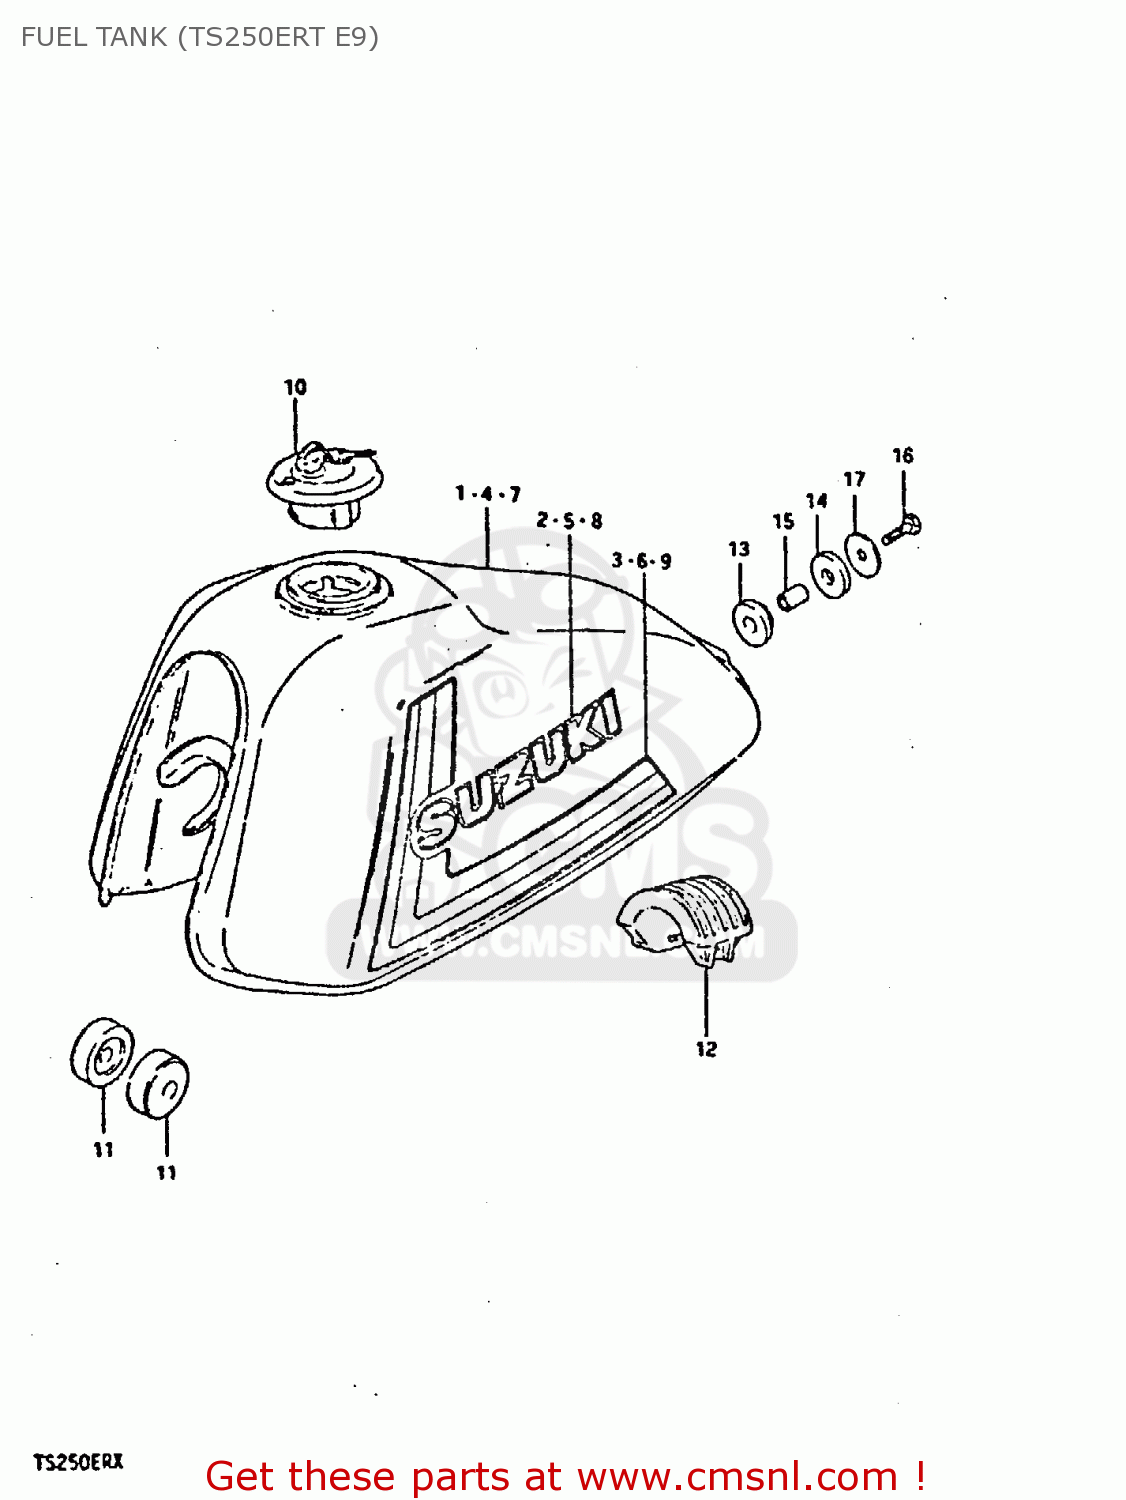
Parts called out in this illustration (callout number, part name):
1	TANK, FUEL (RED)
2	EMBLEM
3	TAPE SET
4	TANK, FUEL (YELLOW)
5	EMBLEM(BLACK)
6	TAPE SET
7	TANK, FUEL (WHITE)
8	EMBLEM(BLACK)
9	TAPE SET
10	CAP SET,FUEL TANK
11	CUSHION
12	CUSHION,FUEL TANK
13	CUSHION
14	CUSHION
15	SPACER (8.2X12X17)
16	BOLT (8X30)
17	WASHER (8.5X29X1.6)
